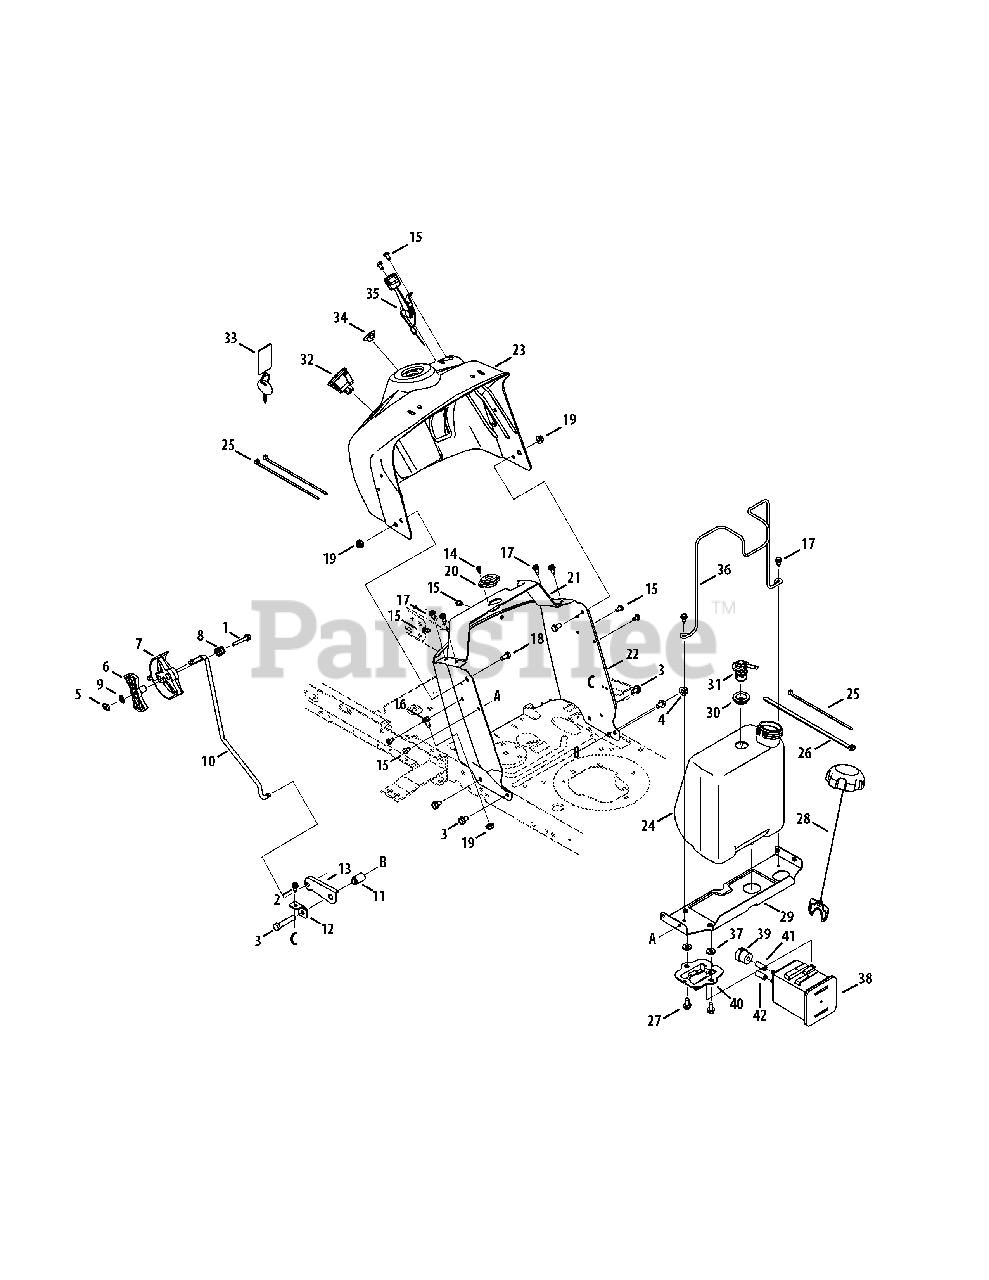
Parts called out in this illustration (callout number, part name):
1	Hex Head Screw, 1/4-20 x 1.50
2	Self-Tap Screw, 1/4-20 x .625
3	Hex Head Screw, 3/8-16 x 2.00
4	Flange Lock Nut, 3/8-16
5	Top Lock Weld Nut, 1/4-20
6	Index Control
7	Shift Lever
8	Compression Spring, .685 x .63
9	Internal Lock Washer, 1/4
10	Speed Control Rod
11	Flange Spacer, .390 x .671 x 1.095
12	Speed Latch Tab
13	Speed Latch
14	Screw, #10
15	Self-Tap Screw, 1/4-20
16	Self-Tap Screw, 5/16-18
17	Hex Washer Screw, 1/4-20 x .625
18	Hex Head Screw, 5/16-18
19	Flange Lock Nut, 5/16-18
20	Steering Column Bearing
21	Steering Support Bracket
22	Lower Dash
23	Upper Dash Panel
24	Fuel Tank
25	Cable Tie, 3/16 x 7.4"
26	Cable Tie, 36" Lg.
27	Screw, 5/16-18 x .750
28	Fuel Cap, 2.25", Carb
29	Gas Tank Support Bracket
30	Rubber Grommet
31	Fuel Rollover Valve
32	Key Switch Module
33	Key Assembly
34	Choke Plug
35	Throttle/Choke Assembly
36	Fuel Tank Support Rod
37	Flat Washer, .344 x .750 x .120
38	5 Gallon Carbon Canister
39	Vent Filter Canister
40	Canister Adaptor Bracket
41	Hose, Fuel, Low Perm., White
42	Hose, Fuel, Low Perm., Yellow
